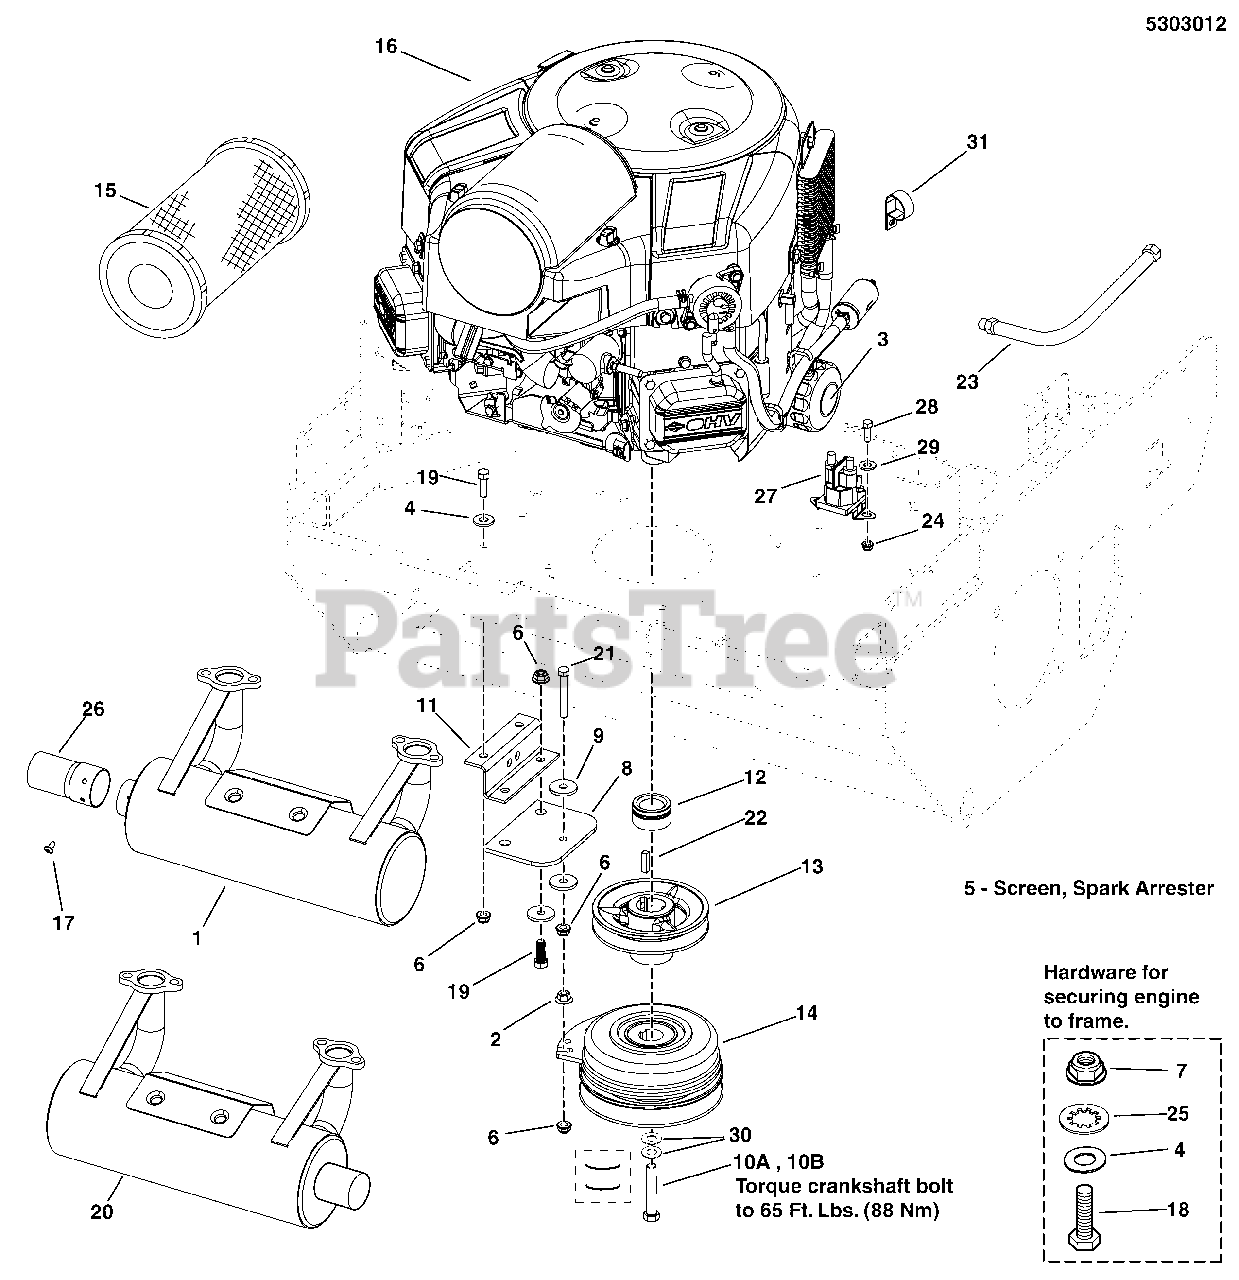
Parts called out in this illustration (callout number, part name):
1	MUFFLER, B&S
2	NUT, 5/16-18 HEX SERRATED FLANGE (LARGE)
3	OIL FILTER, BRIGGS & STRATTON
4	WASHER, 5/16" SAE
6	NUT, 5/16-18 HEX NYLOCK FLANGE
7	NUT, 5/16-24, NYLOCK FLANGE, GD8, CZ
8	CLUTCH ANCHOR PAD
9	WASHER, .34 X 1.25 X 10 GA
11	ANCHOR, CLUTCH - BLK
12	SPACER, 1.13 X 1.75 X 1.35, YZ
13	PULLEY, 4.75 OD X 1-1/8 BORE, BC-48
14	* CLUTCH, 5218-134, WARNER
15	FILTER-AIR CLEANER
16	ENGINE, B&S, COMM TURF
17	SCREW,SELF-TAP,#8-32 X 3/8,WASH HEX, CZ
18	BOLT, 5/16-24 X 1-3/4, GD8
19	BOLT, 5/16-18 X 1 GD5 YZ
20	MUFFLER, RIGHT OUTLET ASSY
21	BOLT, 5/16-18 X 2-1/4 TFL, GD5 YZ
22	KEY, 1/4 SQ. X 1.25
23	HOSE, OIL DRAIN
24	NUT, 1/4-20 HEX SERR. FLANGE
25	WASHER, 5/16 INT. TOOTH LOCK
26	EXTENSION, TAILPIPE, 3" - BLK
27	SOLENOID-4 POLE 12 VOLT DC (TROMBETTA)
28	BOLT,1/4-20X5/8
29	WASHER, 1/4 SAE (5025154)
30	BELLEVILLE WASHER 1.1875 X .442 X .089
31	CLAMP, VINYL INSULATED
